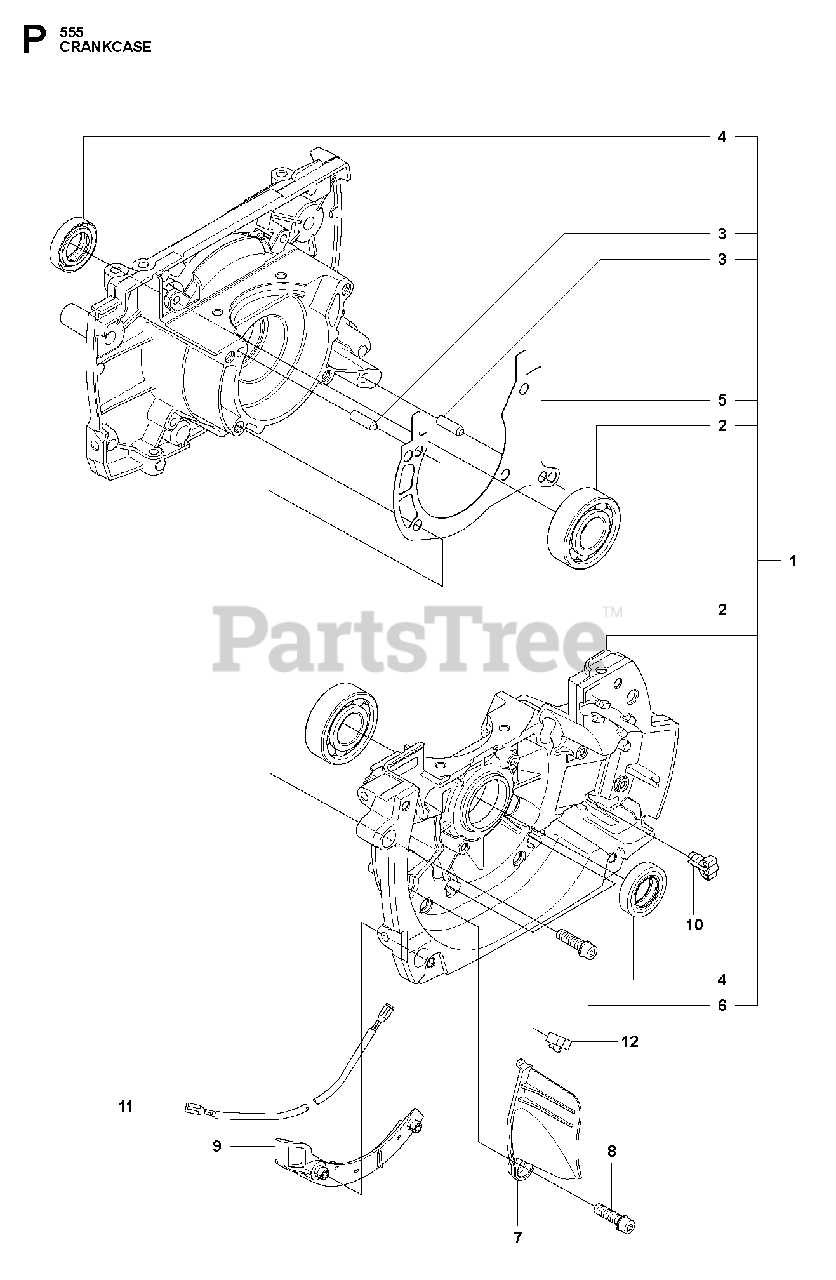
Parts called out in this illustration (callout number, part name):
1	CRANKCASE
2	BALL BEARING
3	PIN 5X14
4	SEALING RING
5	CRANKCASE GASKET
6	SCREW MC6S 5X25
9	CABLE HOLDER
11	SHORT CIRCUIT CABLE
